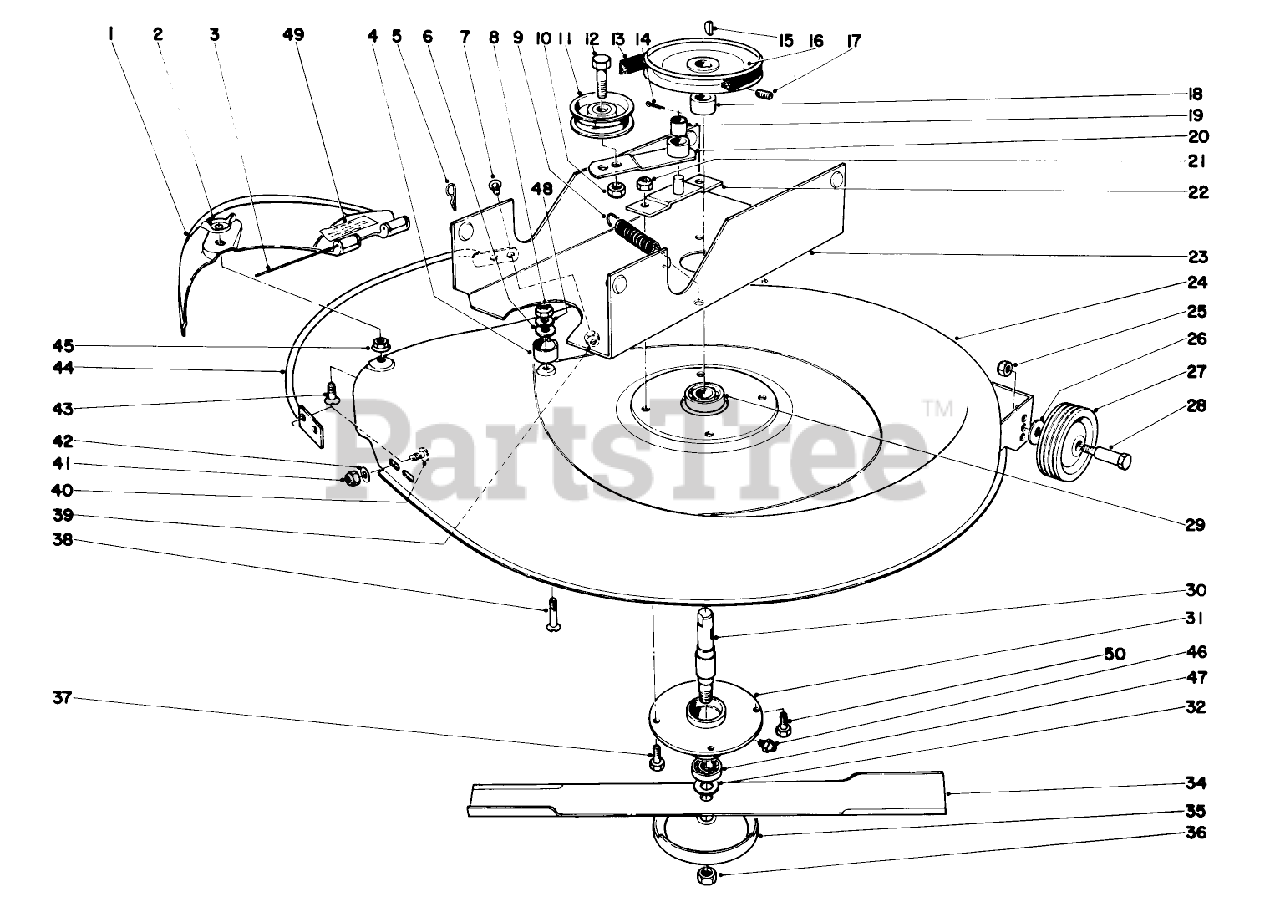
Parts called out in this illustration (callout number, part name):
3	Hinge Pin
5	PIN-COTTER
6	WASHER-FLAT
8	NUT-HEX
12	SCREW-HH
14	PIN-COTTER
15	KEY-WOODRUFF
17	SCREW-HSH
19	Bushing
24	Housing
26	WASHER-FLAT
27	Wheel
31	MOWER SPINDLE HOUSING
32	WASHER
34	Blade
37	SCREW-HH
42	WASHER-FLAT
43	5/16-18X7/8 FLT HD MS
46	FITTING-GREASE
48	WASHER-LOCK
50	SCREW-HH
